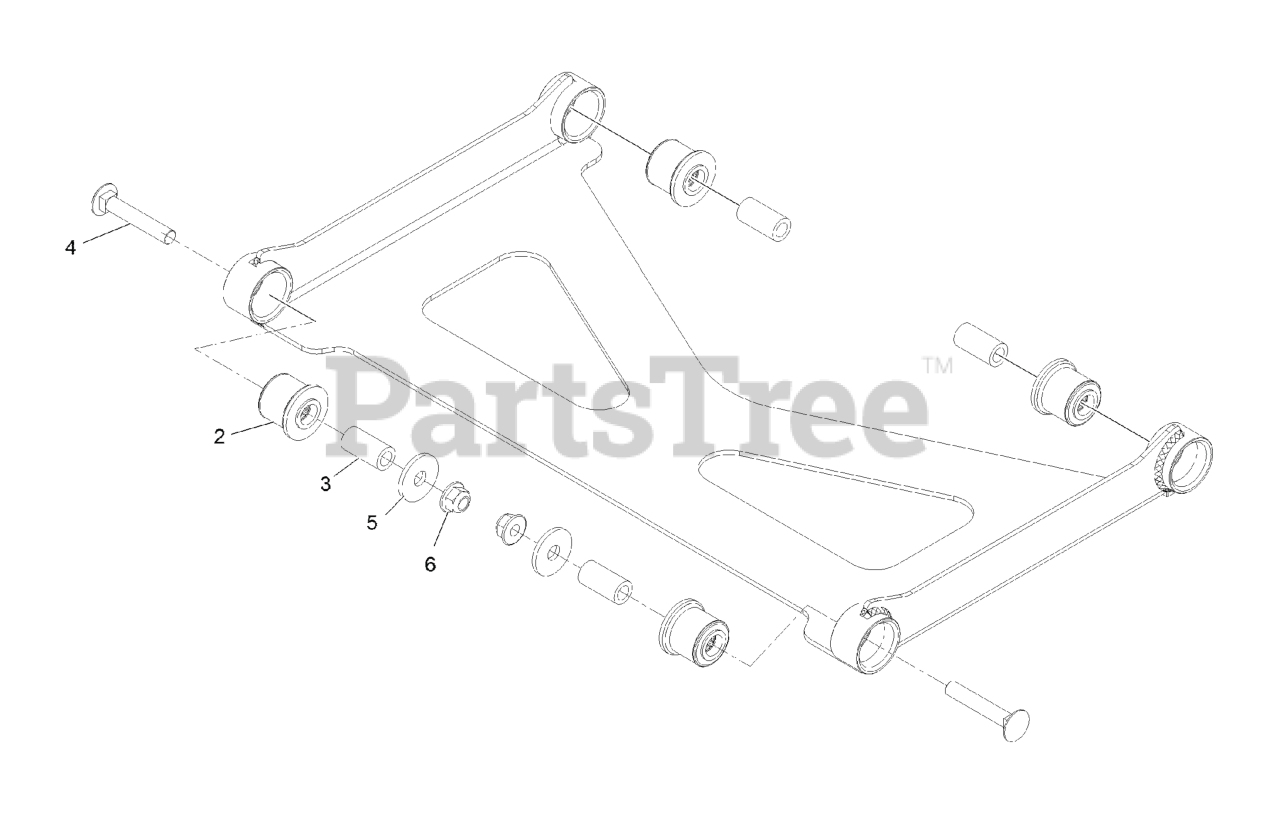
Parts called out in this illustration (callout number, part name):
2	BUSHING-RUBBER, SUSPENSION
4	Bolt-Carriage 3/8-16 X 2 1/4
5	WASHER
6	NUT-HF, NI
